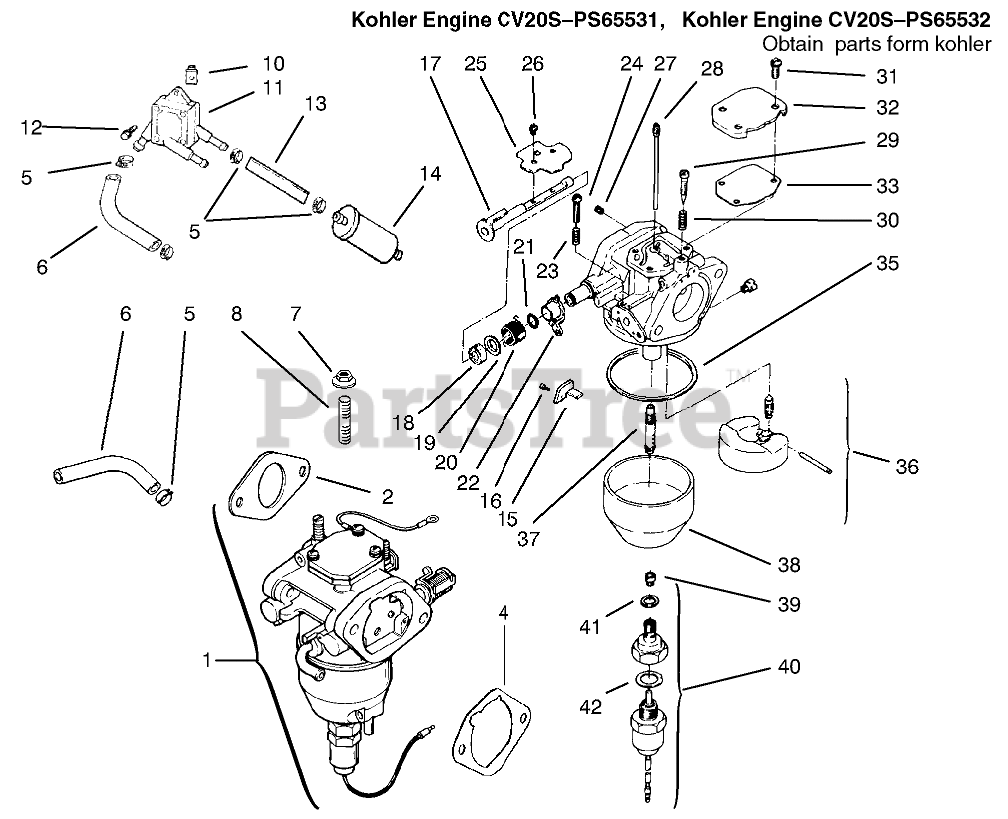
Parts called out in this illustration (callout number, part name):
1	Kit-Carb INC2/4/15-42
2	Kit-Carburetor
4	Gasket-A/C Base
5	Clamp
6	Line-Fuel
9	Line-Fuel 12"
10	Nut
11	Pump-Fuel
12	Screw
13	Line-Fuel
14	Filter-Fuel
15	Bracket-Throttle Stop
16	Screw
17	Shaft-Choke
18	Washer
19	Collar-Coke
20	Spring-Choke Return
21	Ring-Choke Lever
22	Lever-Choke
23	Sprin-Throttle Screw
24	Screw-Throttle Adjust
25	Valve-Choke
26	Screw
27	Jet-Air Bleed
28	Jet-Slow
29	Screw
30	Spring-idler Screw
31	Screw
32	Cover-Passage
33	Gasket-PassageCover
35	Gasket-FloatChamber
36	Kit-Float Repair
37	Nozzle-Main
38	Chamber-Float
39	Jet-Main
40	Kit-Solenoid INC41-42
41	Gasket-ChamberScrew
42	Gasket-Solenoid
